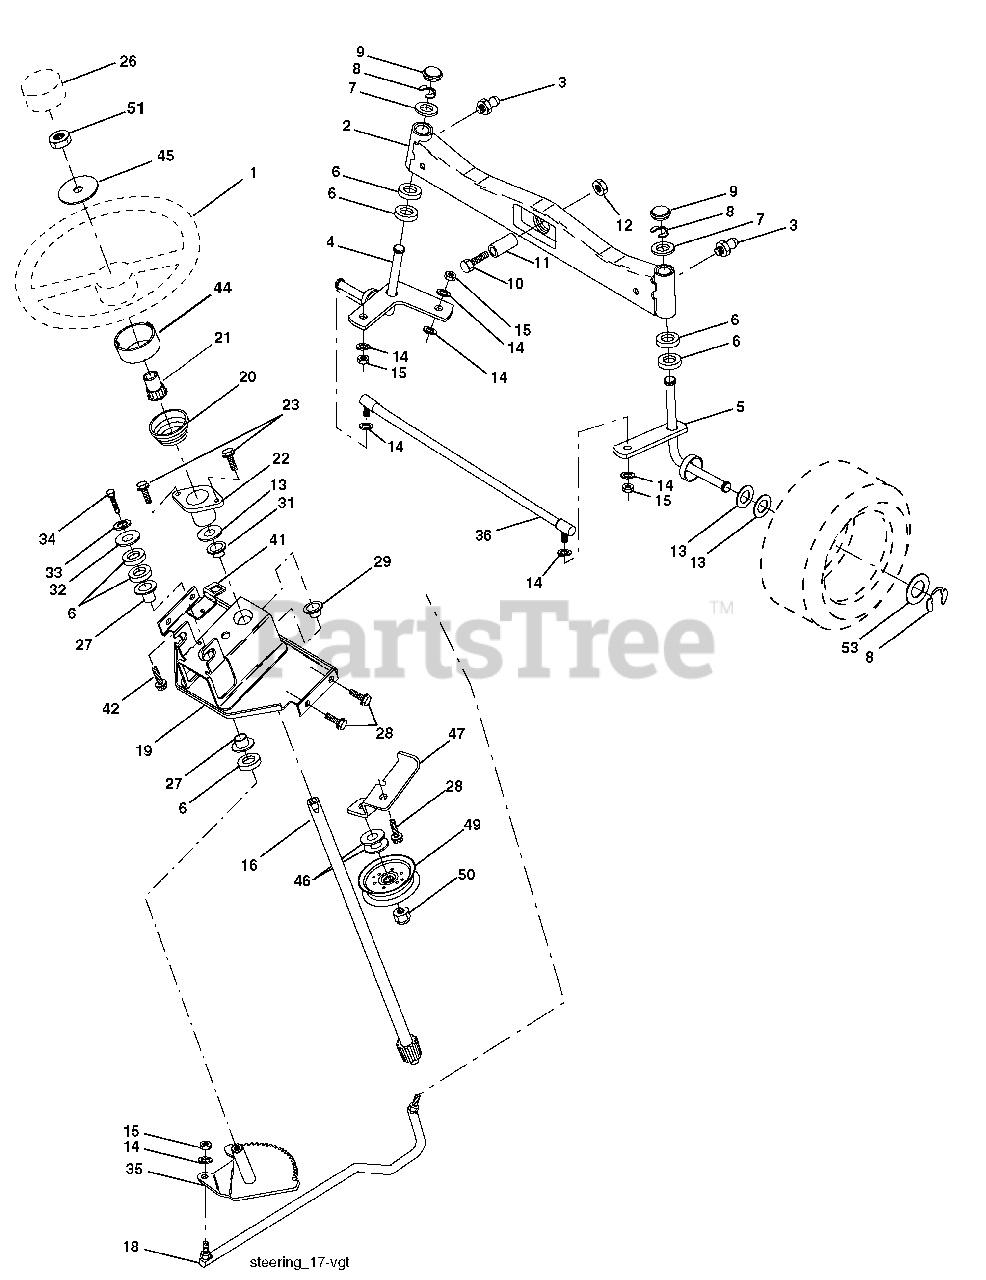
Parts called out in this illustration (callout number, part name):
1	Wheel, Steering
2	Axle Asm., Front
3	Fitting, Grease
4	Spindle Asm, LH
5	Spindle Asm., RH
6	Bearing, Race Thrust Harden
7	Washer 25/32 x 1-5/8 x 16 Ga.
8	Ring, Klip #T5304-75
9	Cap, Spindle
10	Bolt, Fin Hex 5/8-11 x 2-3/4
11	Spacer, Brg. Axle Front
12	Nut, Lock Flange 5/8-11 unc
13	Washer 25/32 x 1-1/4 x 16 Ga.
14	Washer, Lock Hvy Hlcl Spr 3/8
15	Nut Lock Center 3/8-24 unf
16	Shaft Asm., Steering
18	Draglink, Ball Joint Solid Vgt
19	Support Asm., Steering Vgt
20	Boot Steering Stealth
21	Adapter, Wheel Steering
22	Bushing, Strg.
23	Screw
26	Insert Cap Strg WH
27	Bearing, Col. Strg.
28	Screw Hexwsh thdr 3/8-16 x 3/4
29	Bearing, Flange
31	Bushing, Nyliner Snap
32	Washer 11/32 x 1 x 10 Ga.
33	Washer, Lock Hvy Hlcl Spr 5/16
34	Bolt, Hex Hd 5/16-18 x 3/4
35	Gear, Sector Steering
36	Tie Rod
41	Bracket Switch Interlock Vgt 97
42	Screw Thdrol 5/16-18 x 1/2 Tyt
44	Extension Steering
45	Washer 9/16 ID x 2-3/8 OD 12 Ga.
46	Washer 13/32 x 1 x 10 Ga.
47	Bracket Asm. Idler Stationary
48	Screw 3/8-16 x .75
49	Pulley Idler Flat
50	Nut Lock Flg. 3/8-16 unc
51	Nut Hex Jam Toplock 1/2-20 unf
53	Washer Harden .793 x 1.637 x .060
